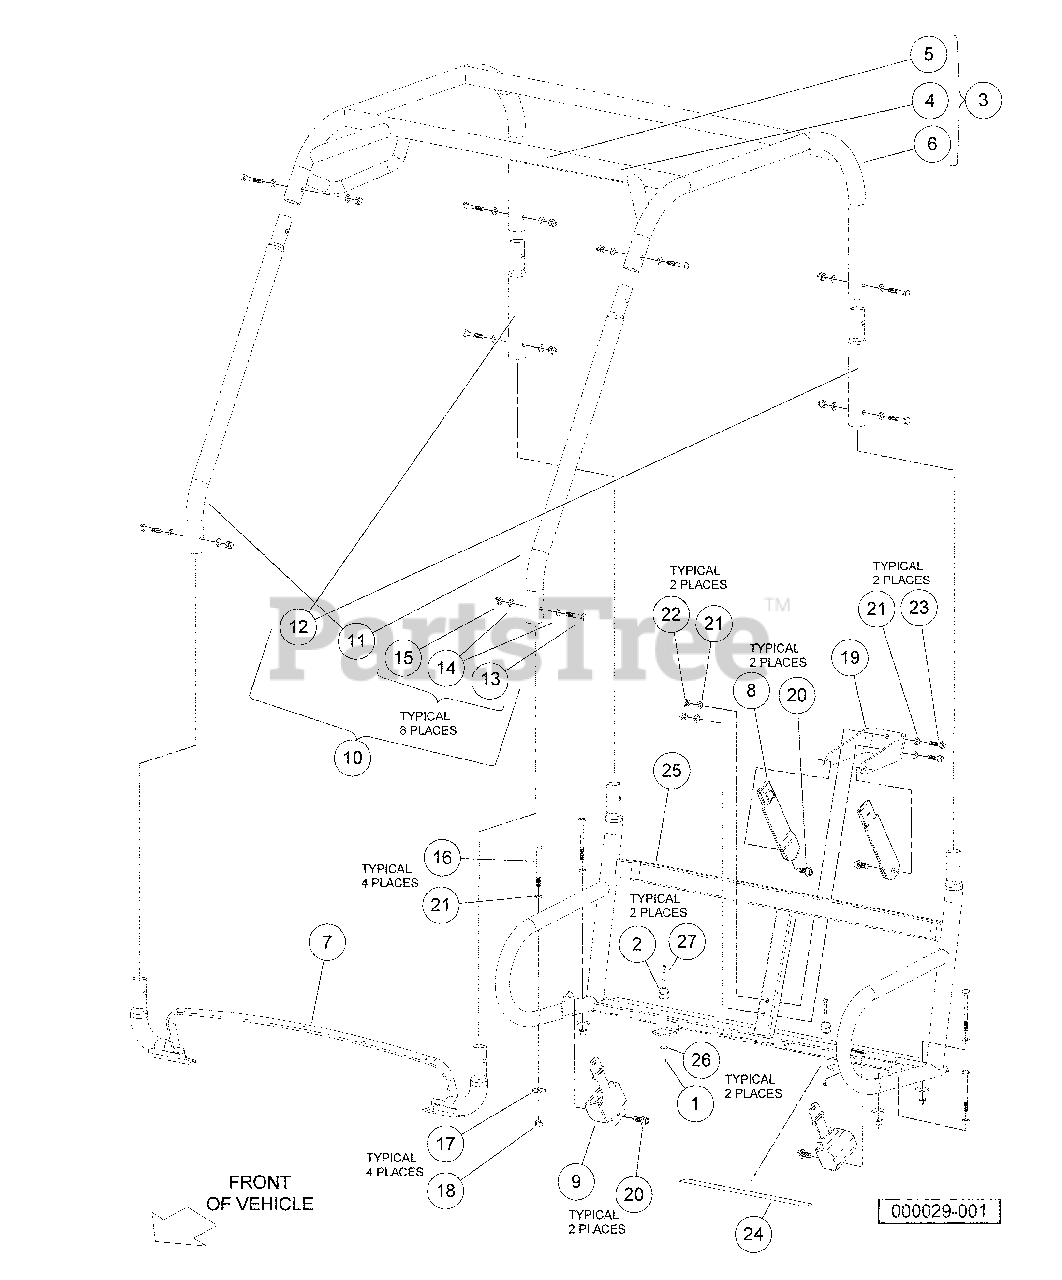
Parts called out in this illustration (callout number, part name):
1	Locknut, M6-1.00 Nylon Insert
2	Seat Holder Base
3	Weldment, Top, ROPS
4	Decal, Young Driver Warning
5	Decal, ROPS Certification/Warning
6	Weldment, ROPS, Top, Unlabeled
7	Weldment, Support, ROPS
8	Buckle, Seat Belt with Sleeve
9	Retractor, Seat Belt
10	Kit, ROPS
11	Tube, Support, Front, ROPS
12	Tube, Support, Rear, ROPS
13	Bolt, M10 X 55, Zn-Ni
14	Washer, Hard, M10, Zn-Ni/Blk
15	Nut, Hex Cap, M10, Zn-Ni/Blk
16	Bolt, M10x1.50x100
17	Washer Hard,m10
18	Nut Flg M10 X 1.5 Mech Def
19	Bracket, Seatbelt, Bolt-On
20	Screw,m12x1.75x30 Thd Form Blk
21	Washer, Hard, M10, Zn-Ni/Blk
22	Nut, Hex Cap, M10, Zn-Ni/Blk
23	Bolt, M10 X 45, Zn-Ni
24	Barrier, Heat, Neoprene
25	Weldment, Supp, Seat, Rops
26	Washer, 1/4 Type A Narrow Flat
27	Bolt, M6 X 1 X 45
